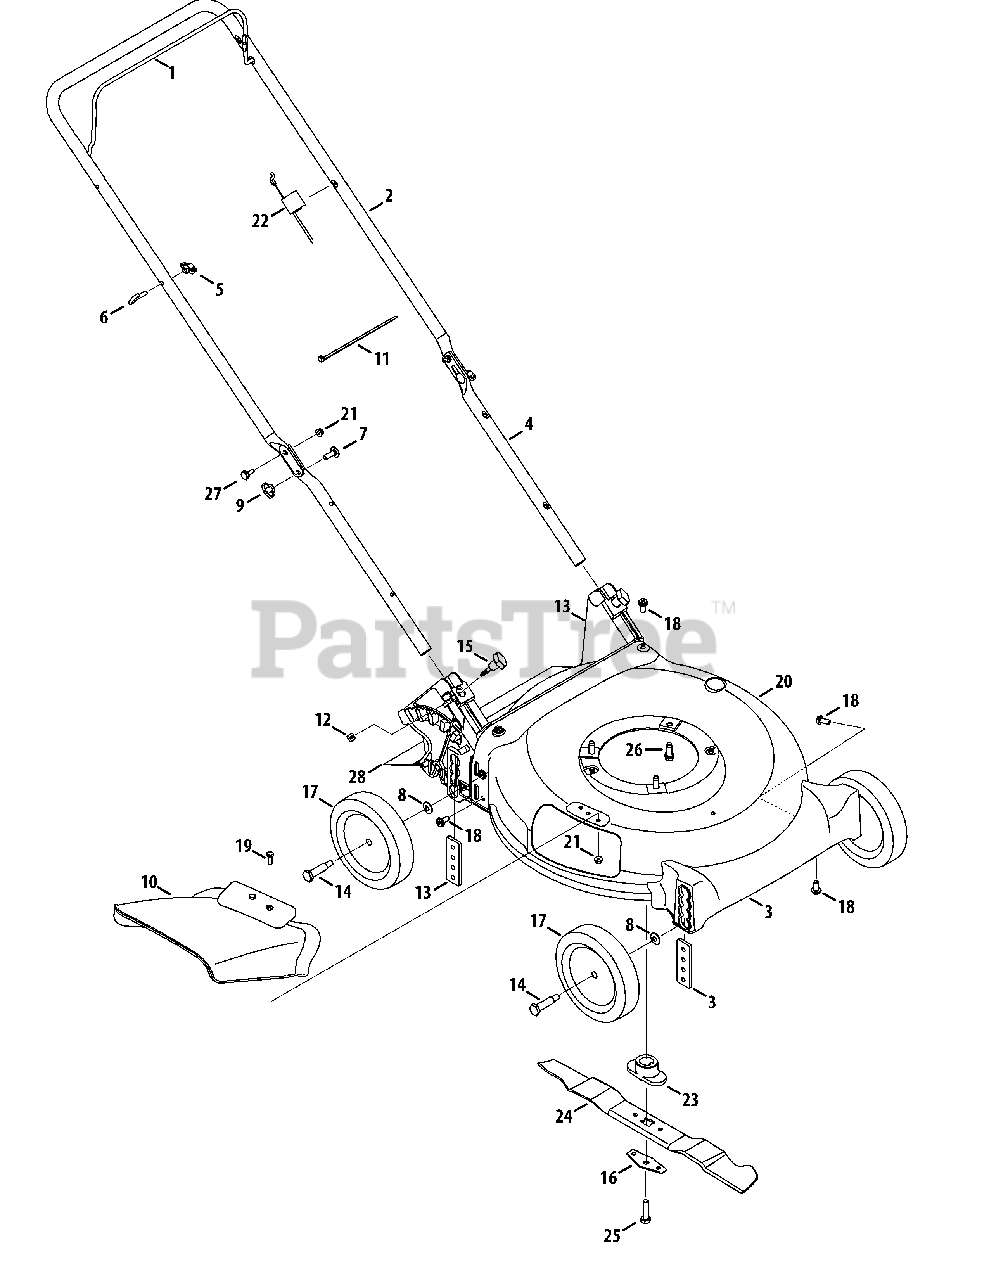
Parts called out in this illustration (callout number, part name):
1	Blade Control
2	Upper Handle
3	Front Cover Assembly
4	Lower Handle
5	Wing Nut
6	Rope Guide
7	Carriage Screw ,5/16-18
8	Washer, .401 x .870 x .060
9	Wing Knob
10	Side Chute
11	Cable Tie
12	Nut, Sq., 1/4-20
13	Rear Baffle
14	Shoulder Screw
15	Wing Nut
16	Blade Bell Support
17	Wheel, 7" Star-Dia., Oys. Gray
18	Screw, 5/16-14 x .750
19	Screw, 1/4-20 x .750
20	Deck , 21"
21	Nut, Flange Lock, 1/4-20
22	Control Cable
23	Blade Adapter
24	Mulching Blade
25	Screw , 3/8-24 x 1.50
26	TT Sems Screw, 3/8-16 x 1.0
27	Sldr. Screw, .375 x .126 x 1/4-20
28	Trail shield
